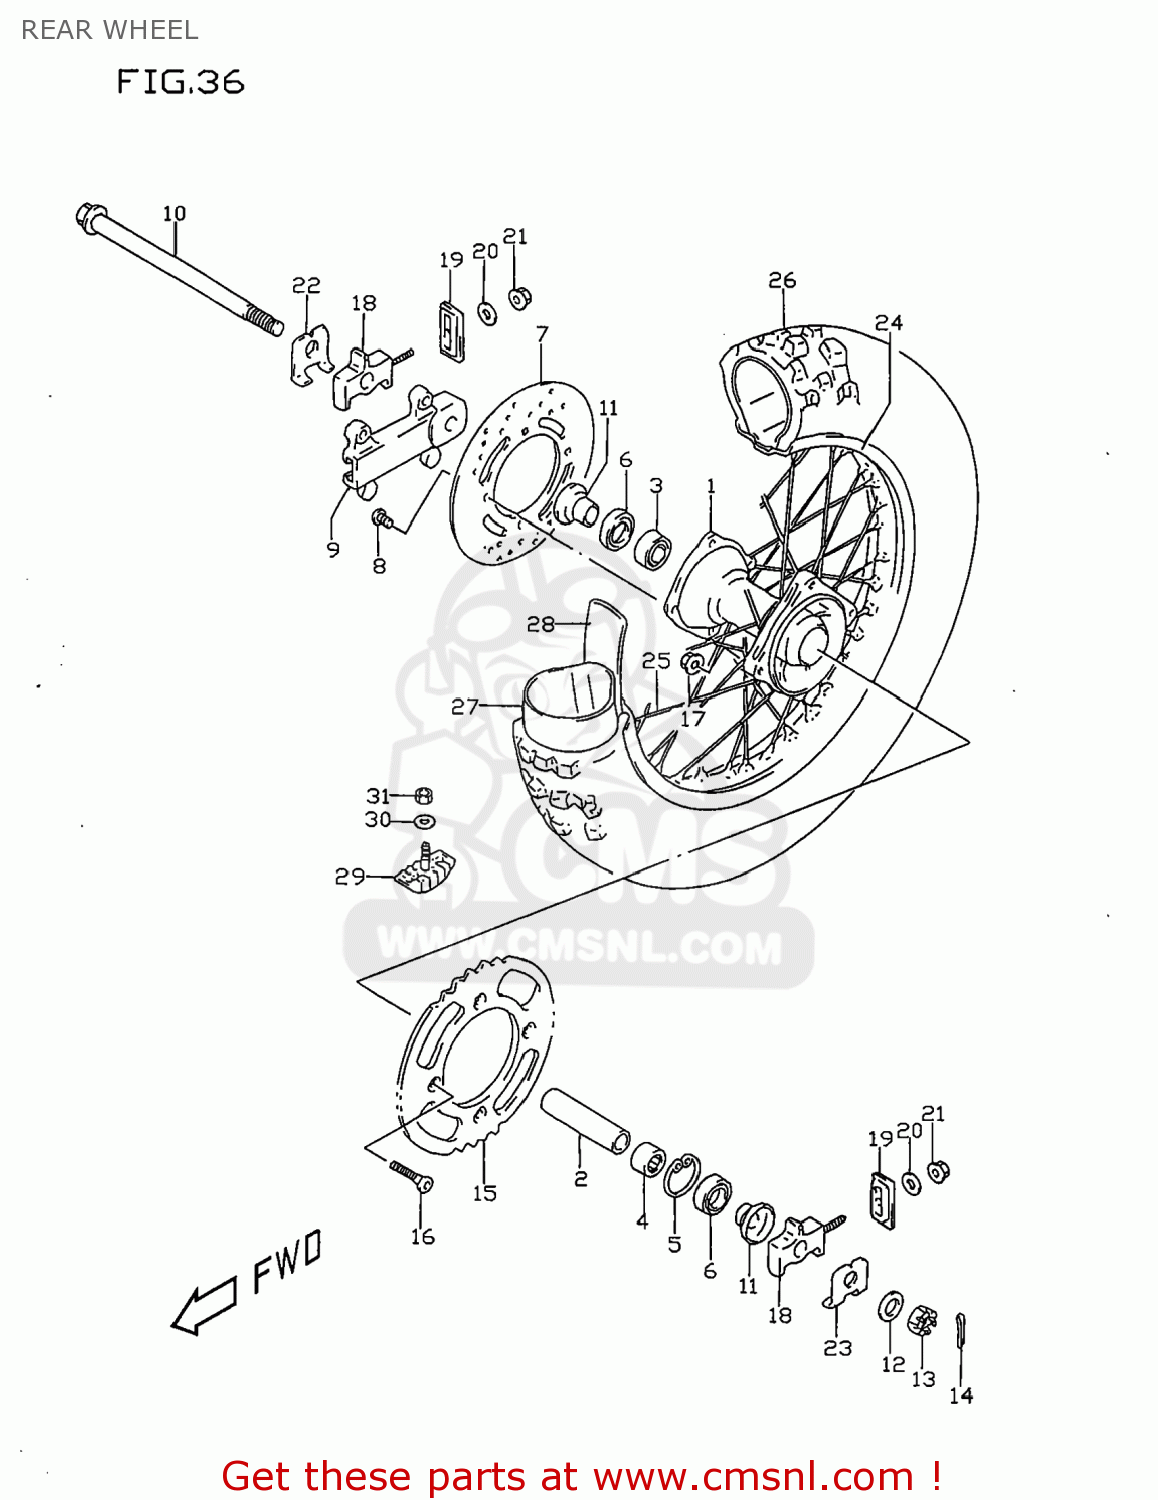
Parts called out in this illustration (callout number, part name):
1	HUB,RR WHEEL
2	SPACER,RR HUB BEARING
3	BEARING
4	BEARING(15X35X11)
5	CIRCLIP
6	SEAL,OIL(20X35X7)
7	DISC,REAR BRAKE
8	SCREW
9	BRACKET,RR AXLE
10	AXLE,RR
11	SPACER,RR AXLE
12	WASHER
13	NUT
14	COTTER PIN
15	SPROCKET,RR(49T)
16	BOLT(8X30.5)
17	NUT
18	ADJUSTER,CHAIN
19	PLATE,CHAIN ADJUSTER
20	WASHER
21	NUT 6MM
22	WASHER,CHAIN ADJUSTER RH
23	WASHER,CHAIN ADJUSTER,L
24	RIM,RR WHEEL(1.60X14 AL)
25	SPOKE ASSY,RR WHEEL
26	TIRE,RR(90/100 14)
27	TUBE ASSY,WHEEL INNER
28	PROTECTOR,WHEEL,INNER
29	STOPPER,BEAD(1.85)
30	WASHER
31	NUT
